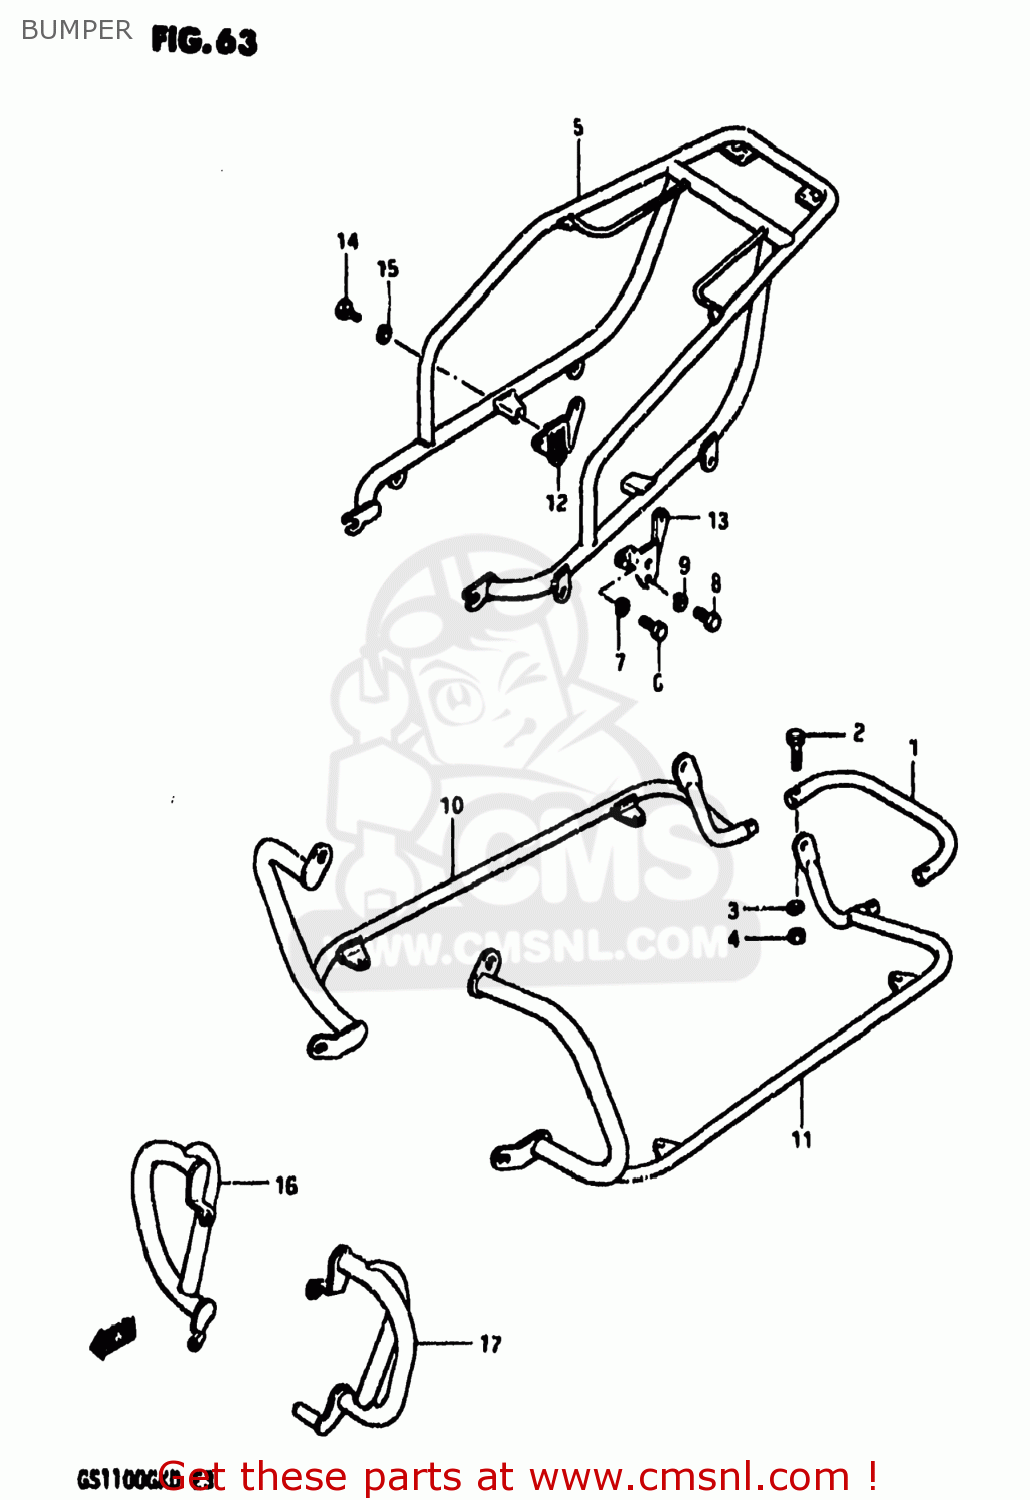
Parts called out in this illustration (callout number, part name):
1	BUMPER,REAR
2	BOLT
3	LOCK WASHER
4	NUT
5	CARRIER TRAVEL TRUNK
6	BOLT
7	LOCK WASHER
8	BOLT
9	LOCK WASHER
10	CARRIER,REAR SIDE,RIGHT
11	CARRIER,REAR SIDE,LEFT
12	BRKT COMP RR CARR R
13	BRKT COMP RR CARR L
14	BOLT
15	LOCK WASHER
16	COVER COMP,ACCESSORY B
17	ACCESSORY BAR,CASE LEFT
